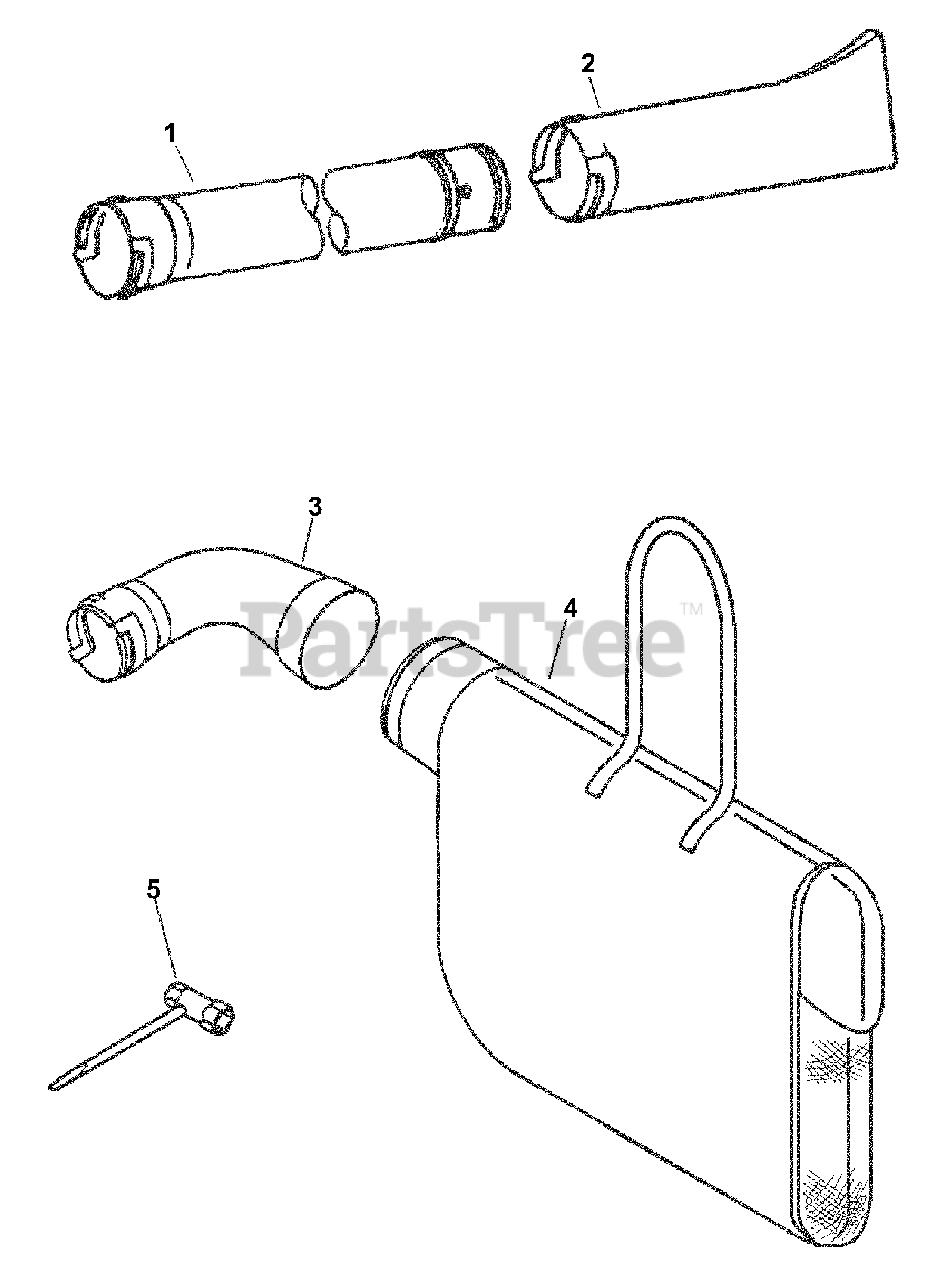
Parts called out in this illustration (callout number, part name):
1	TUBE, BLOWER - STRAIGHT
2	TUBE, BLOWER - NOZZLE
3	TUBE, DEBRIS
4	BAG, DEBRIS
5	T-WRENCH - 13X19mm
